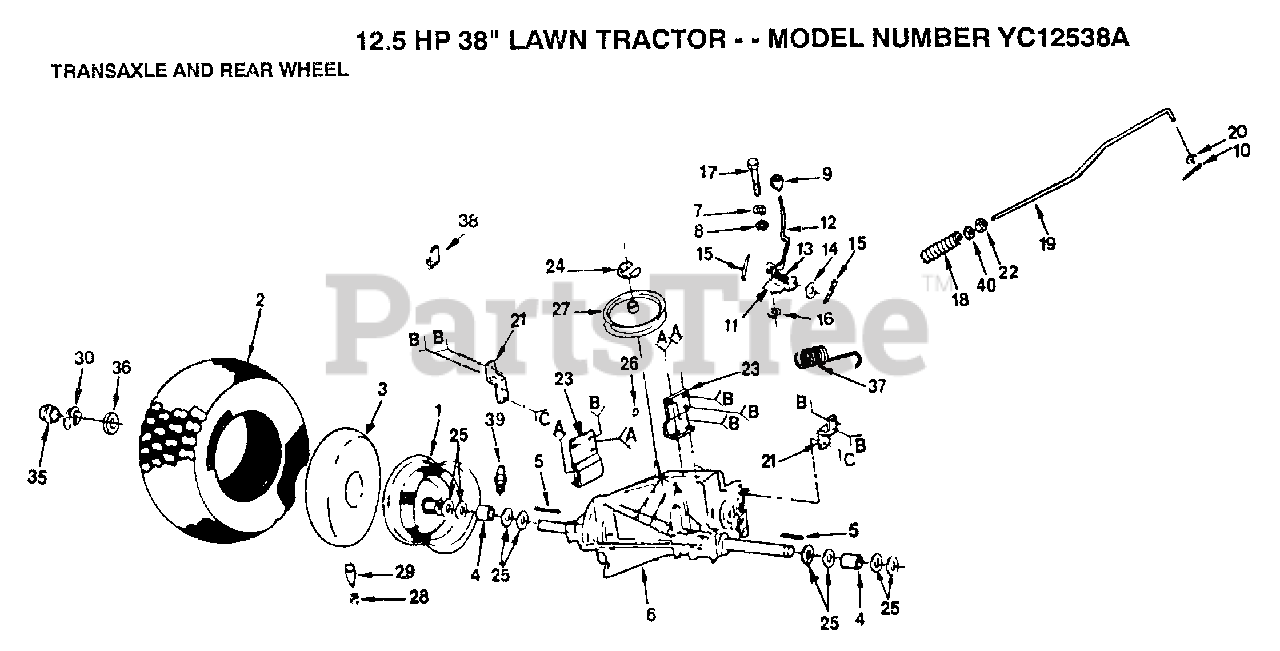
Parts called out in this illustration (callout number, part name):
3	TUBE.18X9.5-8
4	SPACER LT
5	SQUARE KEY
7	LOCKWASHER
8	WASHER LT
9	KNOB.DUCKHEAD.1/2
10	COTTER PIN
11	PLATE SHIFT LT
12	ROD SHIFTER
13	SPRING LT
14	WASHER
15	PIN COTTER 1/8
16	WASH-SHFT PLT LT
18	SPRING ROD LT
19	BRAKE ROD LT
20	WASHER
21	STRAP TORQUE
22	NUT
23	BRACKET LT
25	WASHER
27	PULLEY TRANS
28	VALVE CAP
29	VALVE STEM LT
30	E-RING LT
35	HUB CAP
36	WASHER
38	CLIP T
39	FITTING LT
40	NUT
